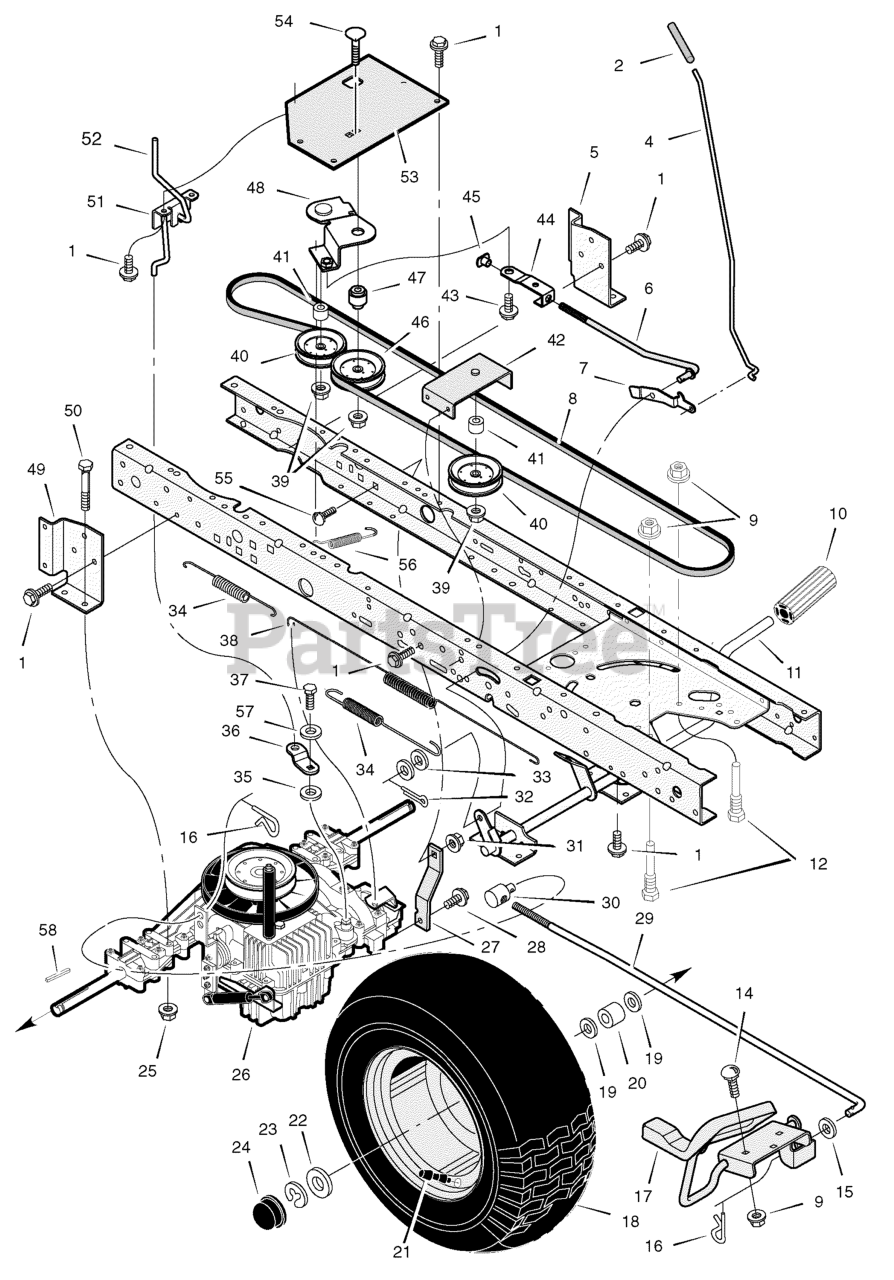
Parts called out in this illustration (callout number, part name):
1	Screw
2	Grip, Parking Brake
4	Rod, Parking Brake
5	Bracket, Transaxle - Left
6	Rod, Clutch
7	Latch, Parking Brake
8	V-Belt, Drive
9	Nut, Flange
10	Pedal, Brake/Clutch
11	Assembly, Brake Pedal
12	Screw, Guide
14	Bolt, Carriage
15	Washer
16	Pin, Hair
17	Pedal Assembly, Hydro
18	Wheel & Tire Assembly - Rear 20" *
19	Washer
20	Spacer
21	Stem, Valve
22	Washer
23	E-Ring
24	Cap, Hub
25	Nut, Centerlock
26	Transaxle **
27	Strap, Torque
28	Screw
29	Rod, Control
30	NUT, Adjusting
31	Nut, Centerlock
32	Pin, Cotter
33	Washer
34	Spring, Extension
35	Washer
36	ARM, Disconnect
37	Capscrew
38	Spring, Brake
39	Locknut, Flange
40	Pulley, Idler
41	Spacer
42	Bracket, Idler Assembly
43	Bolt, Shoulder
44	Link, Clutch
45	Nut, Tee
46	Pulley, Idler
47	Bushing, Pivot
48	Arm Assembly, Idler
49	Bracket, Transaxle -Right
50	Bolt, Hex
51	Bracket, Disconnect
52	Rod, Disconnect
53	Bracket, Idler Pivot
54	Bolt, Carriage
55	Bolt, Carriage
56	Spring, Clutch
57	Washer
58	Key, Square 3/16"
